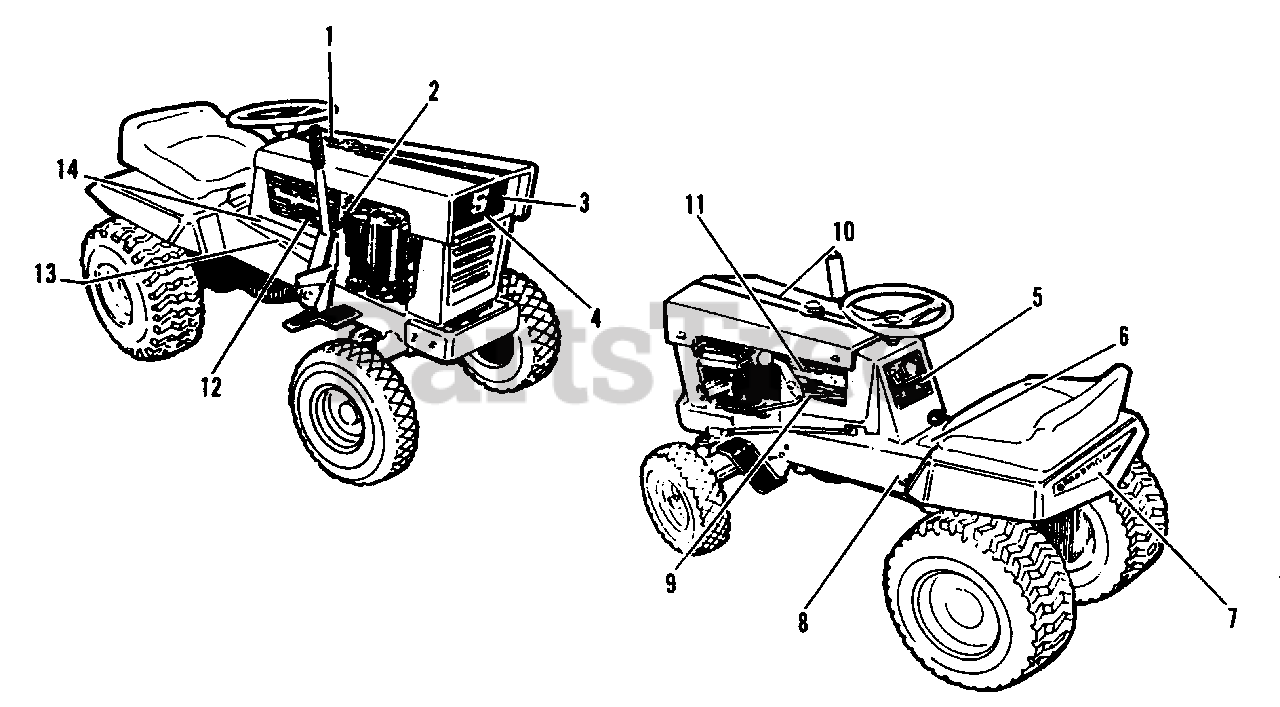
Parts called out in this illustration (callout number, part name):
1	STRIPE, Hood, Rear
2	FILM, Battery
3	DECAL, Grille
5	DECAL, Dash
6	DECAL, Safety & Shift
7	DECAL, Broadmoor
8	FILM, Brake
9	DECAL, P.T.O.
10	STRIPE, Hood, Front
11	DECAL, Simplicity & Number, L.H.
12	DECAL, Simplicity & Number, R.H.
13	DECAL, Clutch
14	FILM, Lift Lever
